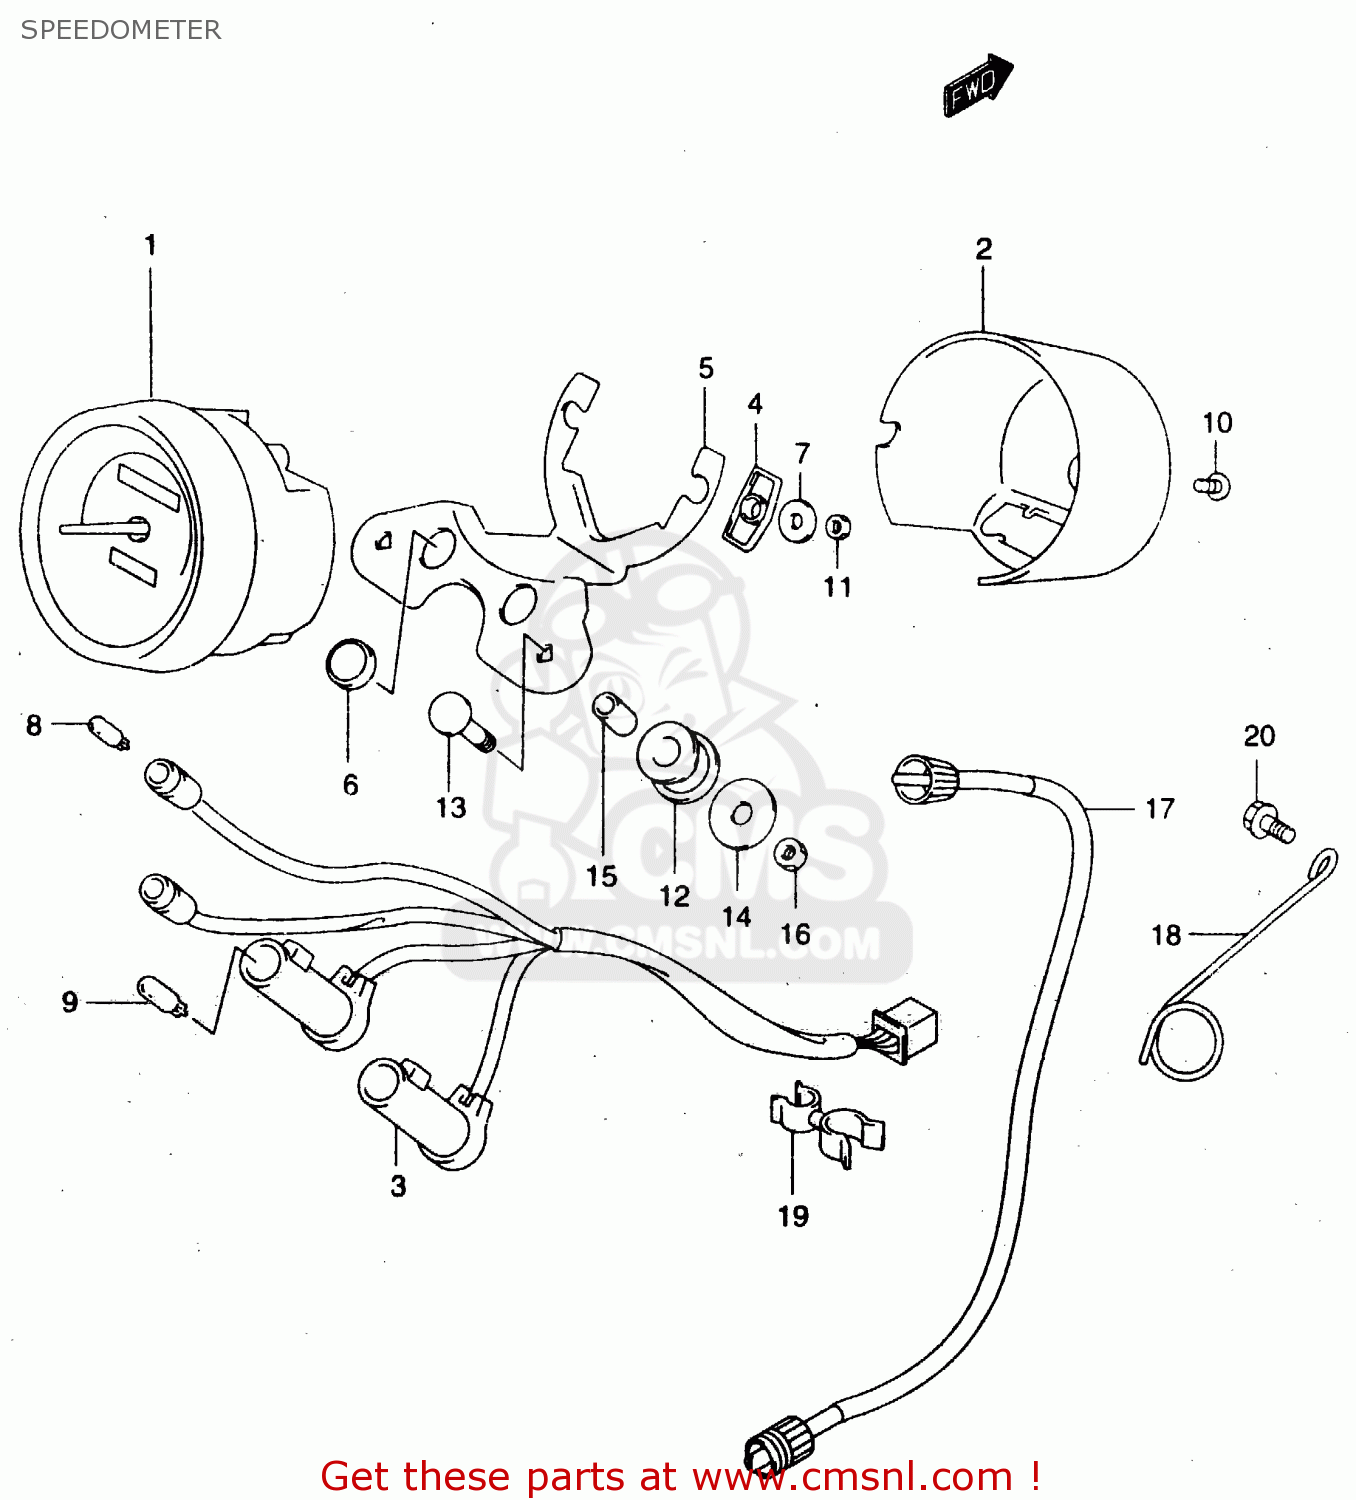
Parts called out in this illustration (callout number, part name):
1	SPEEDOMETER
2	COVER,UNDER(CHROMUN)
3	SOCKET ASSY
4	CUSHION,DAMPER
5	BRACKET,METER
6	LENS(GREEN)
7	WASHER(5.2X16X1)
8	BULB(12V3.4W,T10)
9	BULB(12V1.7W,T6.5)
10	SCREW
11	NUT
12	CUSHION,METER BRACKET
13	BOLT(6X30)
14	WASHER(6.5X28X1.6)
15	SPACER(6.5X10X15.7)
16	NUT 6MM
17	CABLE ASSY,SPEEDOMETER
18	GUIDE,SPEEDOMETER CABLE
19	CLIP
20	BOLT
